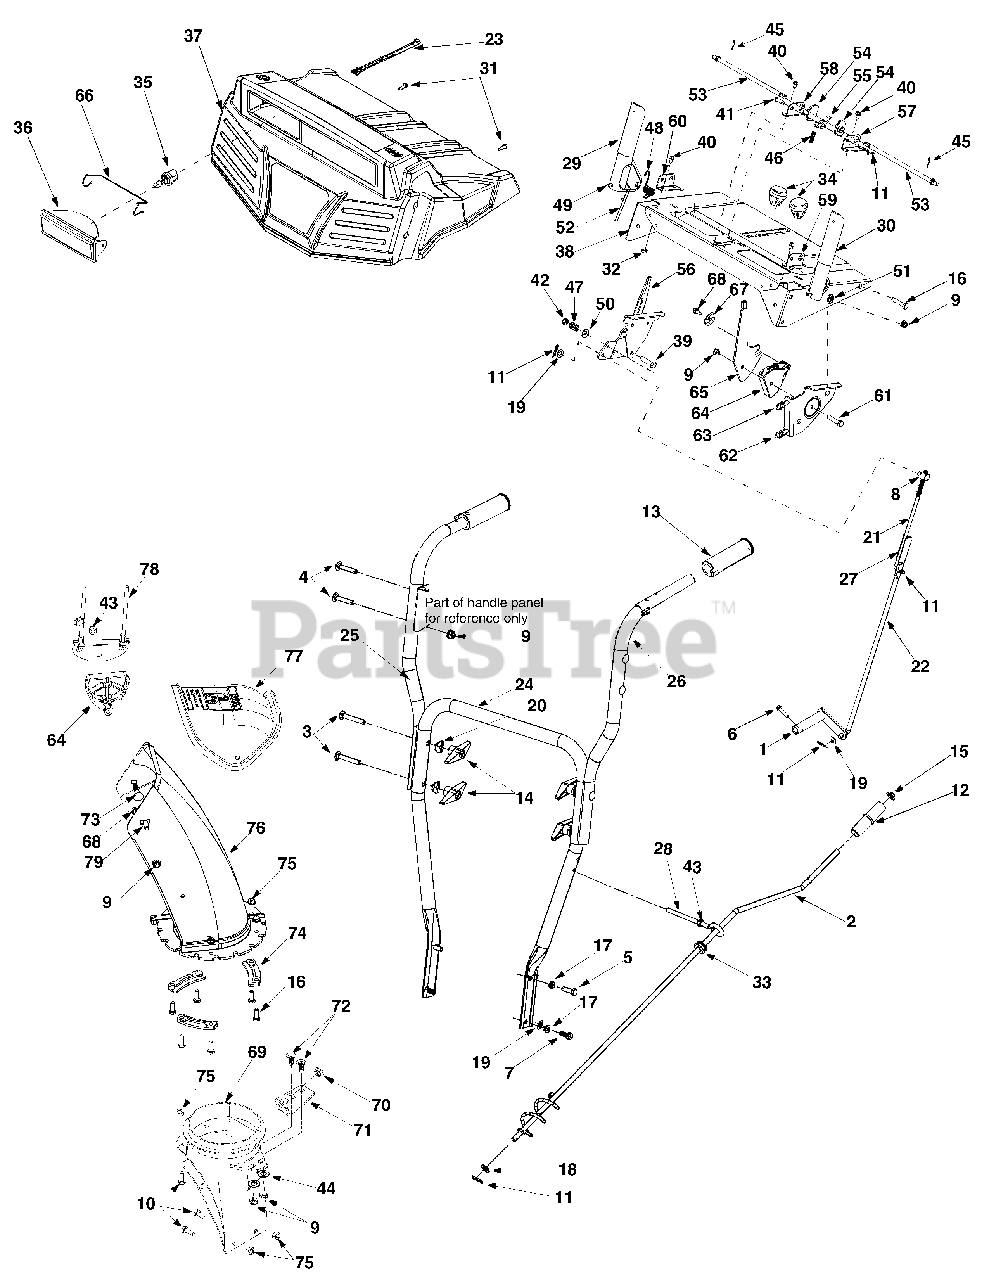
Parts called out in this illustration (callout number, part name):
3	Carriage Screw 5/16-18 x 2.25
4	Carriage Bolt 5/16-18 x 1.75
5	Hex Bolt 5/16-18 x 1.0
6	TT Screw 1/4-20 x 1.0
7	Hex Bolt 5/16-18 x 0.75
8	Ferrule
9	Flange Lock Nut
10	Carriage Screw, 1/4-20 x.75
11	Hairpin Clip
12	Chute Directional Control Knob
14	Handle Knob Assembly
16	Hex Screw, 1/4-20 x 1.00
17	Lock Washer
18	Flat Washer
19	Flat Washer
20	Saddle Washer
21	Upper Shift Rod
22	Lower Shift Rod
23	Light Harness
29	Handle Engagement Assembly RH
30	Handle Engagement Assembly LH
31	B Screw #10-16 x 0.625
32	Hex Sems Nut 1/4-20
33	Rubber Grommet
34	Shift Knob
35	Halogen Lamp, 27W, 12V
36	Lamp Housing
37	Handle Panel
39	Hex Bolt 3/8-24 x 1.5
40	TT Screw 1/4-20 x 0.5
41	Clevis Pin
42	Jam Lock Nut 3/8-24
43	Hex Nut, 5/16-18
44	Flat Washer,.349 x.879 x.063
45	Cotter Pin
46	Compression Spring
47	Compression Spring
48	Torsion Spring
49	Rubber Bumper
50	Bell Washer
51	Flat Washer
52	Drive Cable Z- Fitting
54	Handle Lock Cam
55	Handle Lock Pawl
61	Hex Bolt 5/16-18 x 1.5
62	Chute Deflector Cable w/Clip
63	Chute Deflector Control Cable
64	Chute Cable Guide
66	Headlight Retainer
67	Special Washer
68	Hi-Lo Screw 1/4-15 x 0.75
69	Chute Adapter
70	Plastic Bushing
72	Carriage Screw, 5/16-18 x 1.00
73	Carriage bolt 5/16-18 x 1.5
74	Flange Keeper
75	Flange Lock Nut 1/4-20
76	Lower Chute
77	Upper Chute
79	Carriage Bolt 5/16-18 x 1.0
